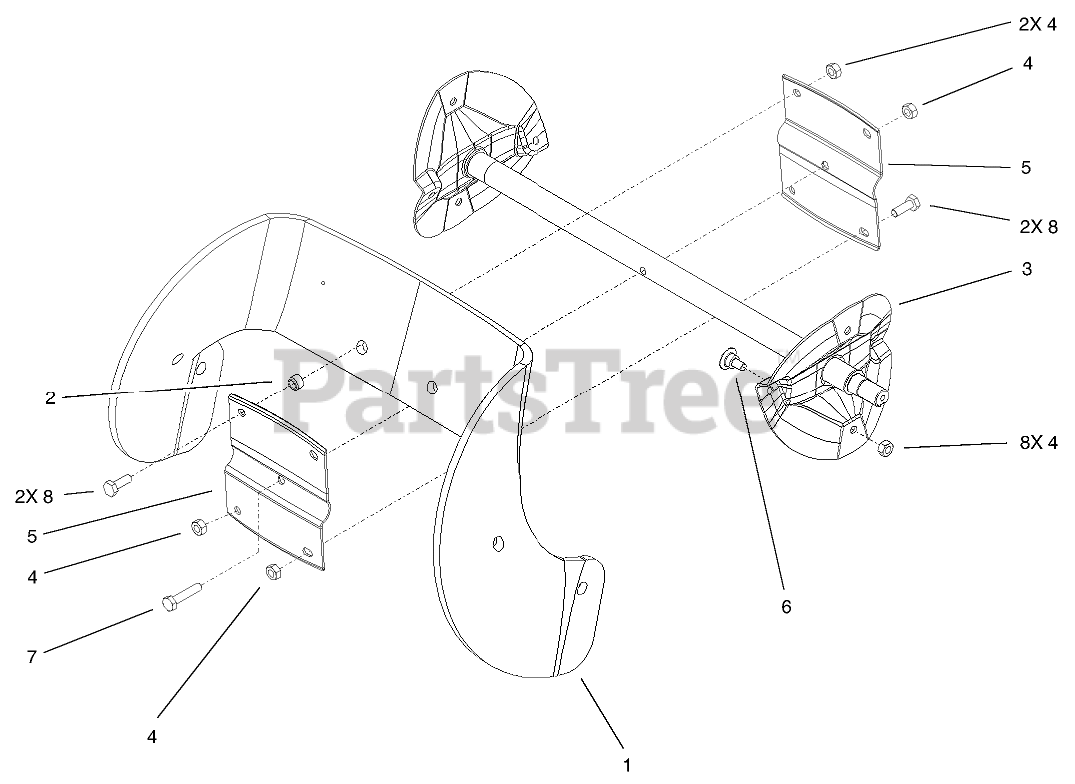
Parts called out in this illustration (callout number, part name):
1	BLADE-ROTOR
2	SPACER-BLADE, ROTOR
3	ROTOR ASM
4	NUT-LOCK, NI
5	HALF-ROTOR
6	SCREW
7	SCREW-HH
8	SCREW-HH
